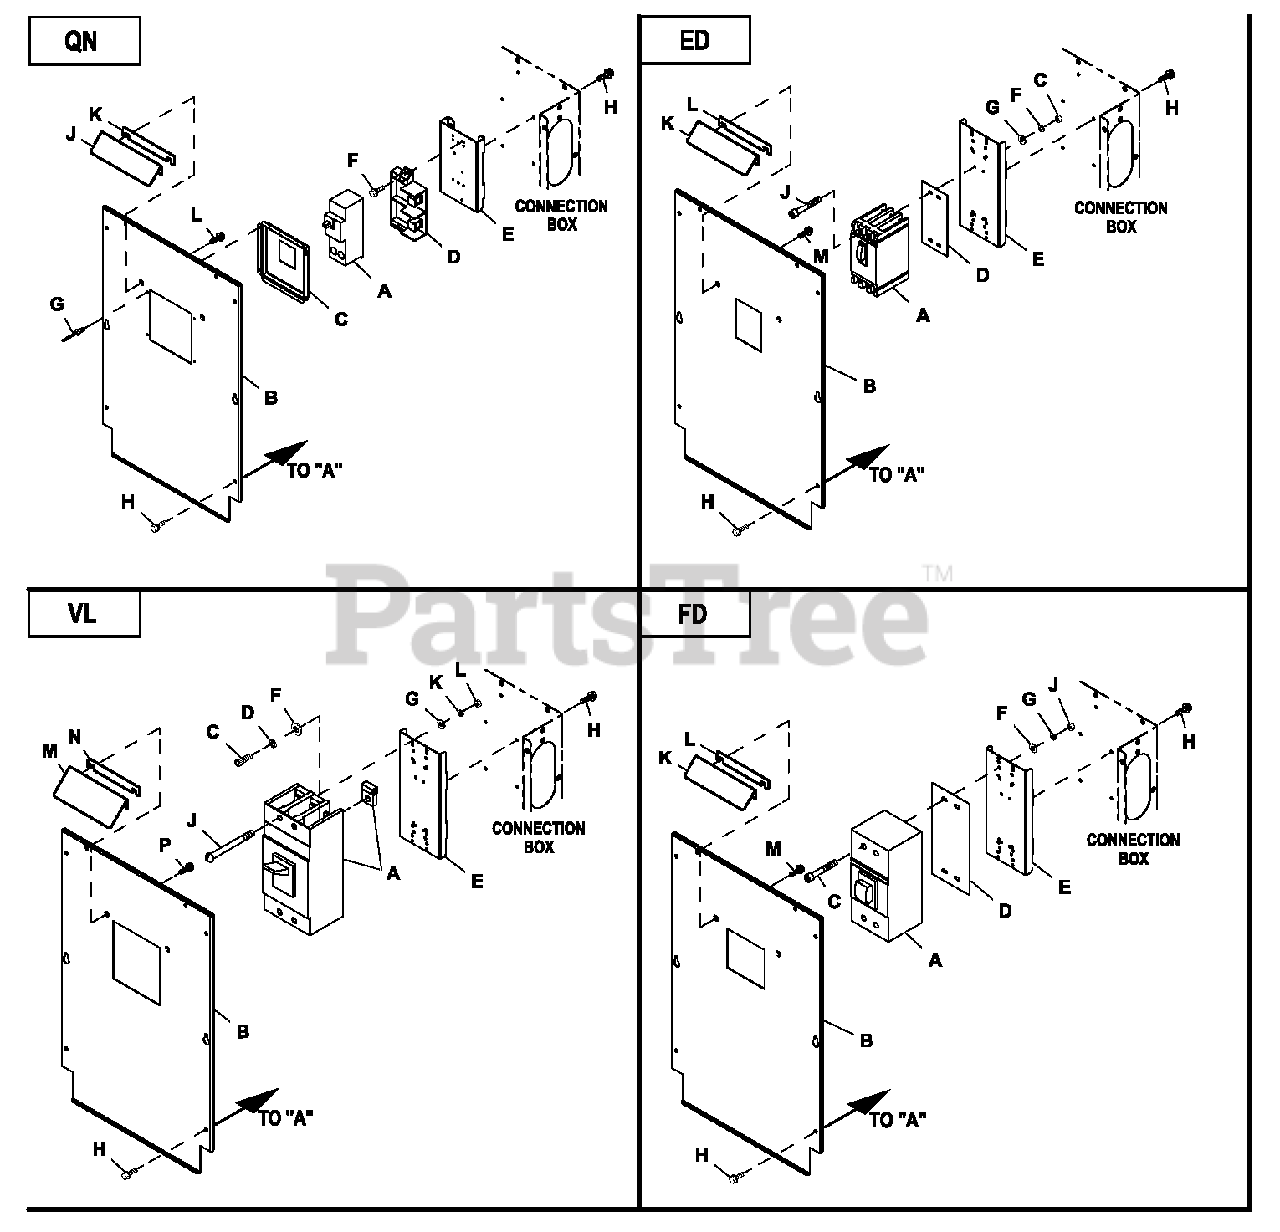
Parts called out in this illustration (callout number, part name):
A	CB 0175A2P 240V S Q N 2 LL
B	COVER CB C2 CPL
C	COVER CB DISH 2P S Q N
D	BASE, Q N CIRCUIT BREAKER
E	STA N DOFF CB BOX CO N BOX
F	SCREW HHTT M5-0.8 X 10 BP
G	RIVET POP .125 X .275 SS
H	SCREW HWHT M6-1 X 16 N WA Z/JS
J	SHIELD-SM CIRCUIT BREAKER
K	GASKET-CB SHIELD C2
L	SCREW HWHTF M6-1.0X16
A	CB 0125A3P 480V S ED4 LL
B	COVER CB S ED C2 CO NBOX
C	N UT HEX #10-32 STEEL
D	I N SULATOR CB S(ED-3P)
E	STA N DOFF CB MOU NT CO N BOX
F	WASHER LOCK #10
G	WASHER FLAT#10ZIN C
J	SCREW RHM #10-32 X 4-1 /2
K	SHIELD-SM CIRCUIT BREAKER
L	GASKET-CB SHIELD C2
M	SCREW HWHTF M6-1.0X16
A	CB 0300A 3P 600V S JG-VL LL
B	COVER CB S JG VL C2 CONBOX
C	SCREW SHC M8-1.25 X 20 C12.9
D	WASHER LOCK M8-5/16
E	STANDOFF CB MOUNT CONBOX
F	WASHER FLAT 5/16-M8 ZINC
G	WASHER F LA T # 1 0 ZINC
J	SCREW RHM 1 0 -3 2 X 4
K	WASHER LOCK #10
L	NUT HEX #10-32 STEEL
M	SHIELD-LGE CIRCUIT BREAKER
N	GASKET-CB SHIELD C2
P	SCREW HWHTF M6-1.0 X 1 6
A	CB 0 1 5 0A 3P 600V S FD6 LL
B	COVER CB S FD6 C2 CONBOX
C	SCREW SHC 1 /4 -2 0 X 4 .5 G8.8 NZ
D	INSULATOR CB FD FRAME 30MIL
F	WASHER FLAT 1/4-M6 ZINC
G	WASHER LOCK M6-1/4
J	NUT HEX 1/4-20 STEEL
M	SCREW HWHTF M6-1.0 X 1 6
